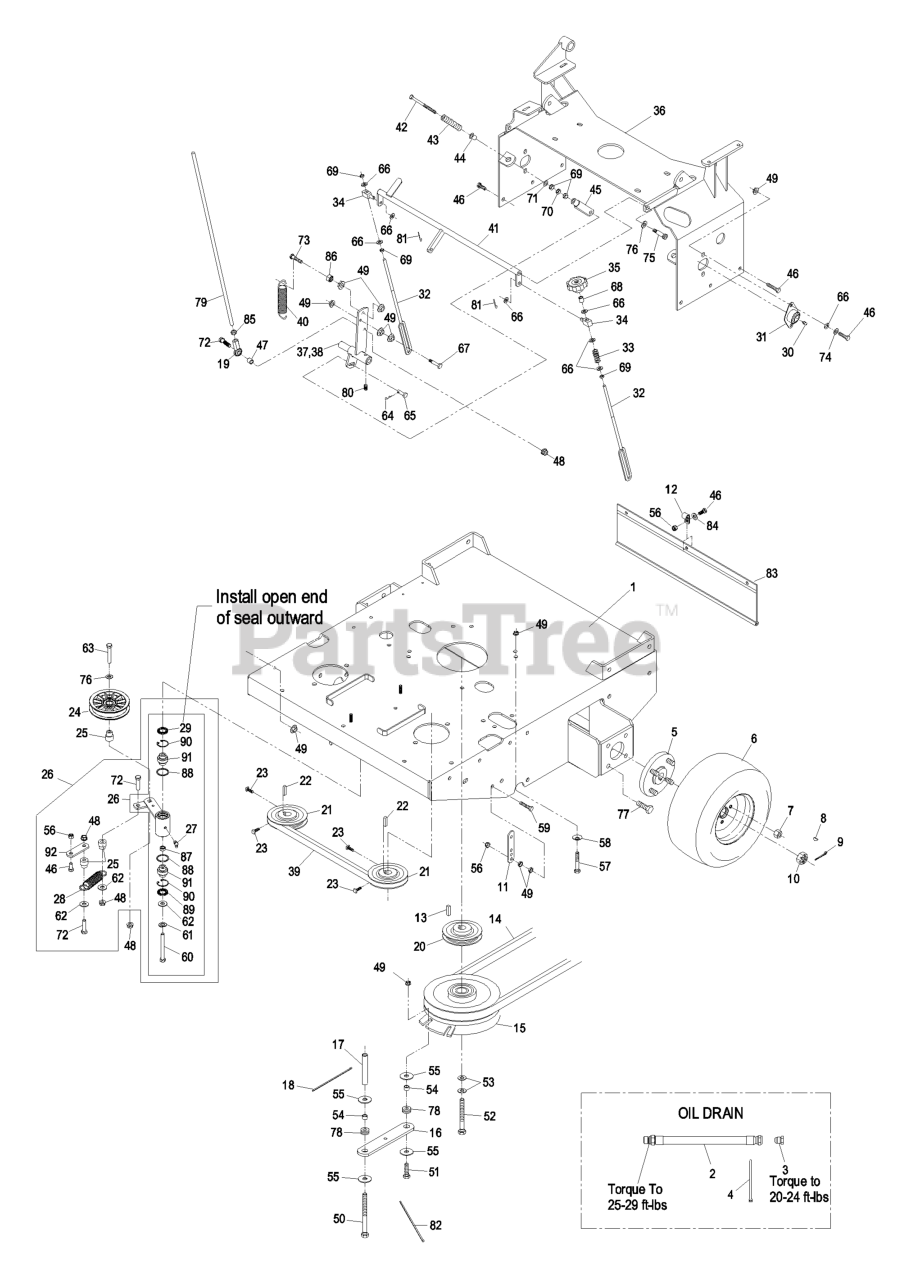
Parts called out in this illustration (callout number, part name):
1	Eng Deck 109-2579-01 W/ Decals
4	TIE-PLASTIC
6	ASM, DRIVE TIRE
7	NUT-LUG
8	KEY-WOODRUFF
9	PIN-COTTER
10	NUT-HEX, SLOTTED
11	TAB-SPRING, EXTENSION
12	CLIP-LOOM
14	BELT,B 83.65
15	CLUTCH ASM
16	STRAP-CLUTCH, BRAKE
17	SPACER,SHIELD
18	TIE-CABLE
19	JOINT-BALL END, LH
20	PULLEY
21	SHEAVE ASM
23	SCREW-SET
24	PULLEY-IDLER, FLAT
25	BUSHING-IDLER
26	KIT,IDLER ARM W/BRGS.
27	FITTING-GREASE, 90 DEG
28	SPRING-EXTENSION
29	SEAL-LIP, SINGLE
30	FITTING-GREASE
31	BEARING-FLANGE, SIDE
32	LINK,SPEED CONTROL
33	SPRING-COMPRESSION
35	KNOB-TRACKING
37	WLD,LH CONTROL ARM
39	BELT,COG A-59.5
40	SPRING-EXTENSION
41	WLD,CRANK SPEED CNTRL
42	BOLT-RETURN, NEUTRAL
43	SPRING,COMPRESSION (NEUT)
44	BUSHING-FLANGED
45	YOKE-ADJUSTABLE
46	SCREW-HH
47	TUBE,PUMP LINK SPACER
48	NUT-HHF, WHIZ
50	SCREW-HH
51	SCREW-HH
52	SCREW-HH
53	WASHER-SPRING
56	NUT-LOCK, NI
57	SCREW-HH
58	WASHER-SPRING
59	BOLT-TAP, HH
60	SCREW-HH
61	WASHER-LOCK
62	WASHER-FLAT
63	SCREW-HH
64	PIN-COTTER
65	PIN-CLEVIS
66	WASHER-PLAIN
67	SCREW-HH
69	NUT-HEX
70	NUT-JAM
71	WASHER-FLAT
72	SCREW-HH
73	SCREW-HH
74	WASHER-LOCK
75	SCREW-HSH
76	WASHER-FLAT
77	SCREW-HHF
78	GROMMET
79	LINK,DRIVE (PLTD)
80	SCREW-SET
81	PIN-COTTER
82	TIE-PLASTIC
83	SHIELD,DRAG
84	WASHER-FLAT
85	NUT-HEX JAM, LH
86	NUT-JAM
89	SEAL-LIP, DOUBLE
90	RING-SNAP
91	BEARING-SPHERICAL
92	ARM-LIFT, DECK
